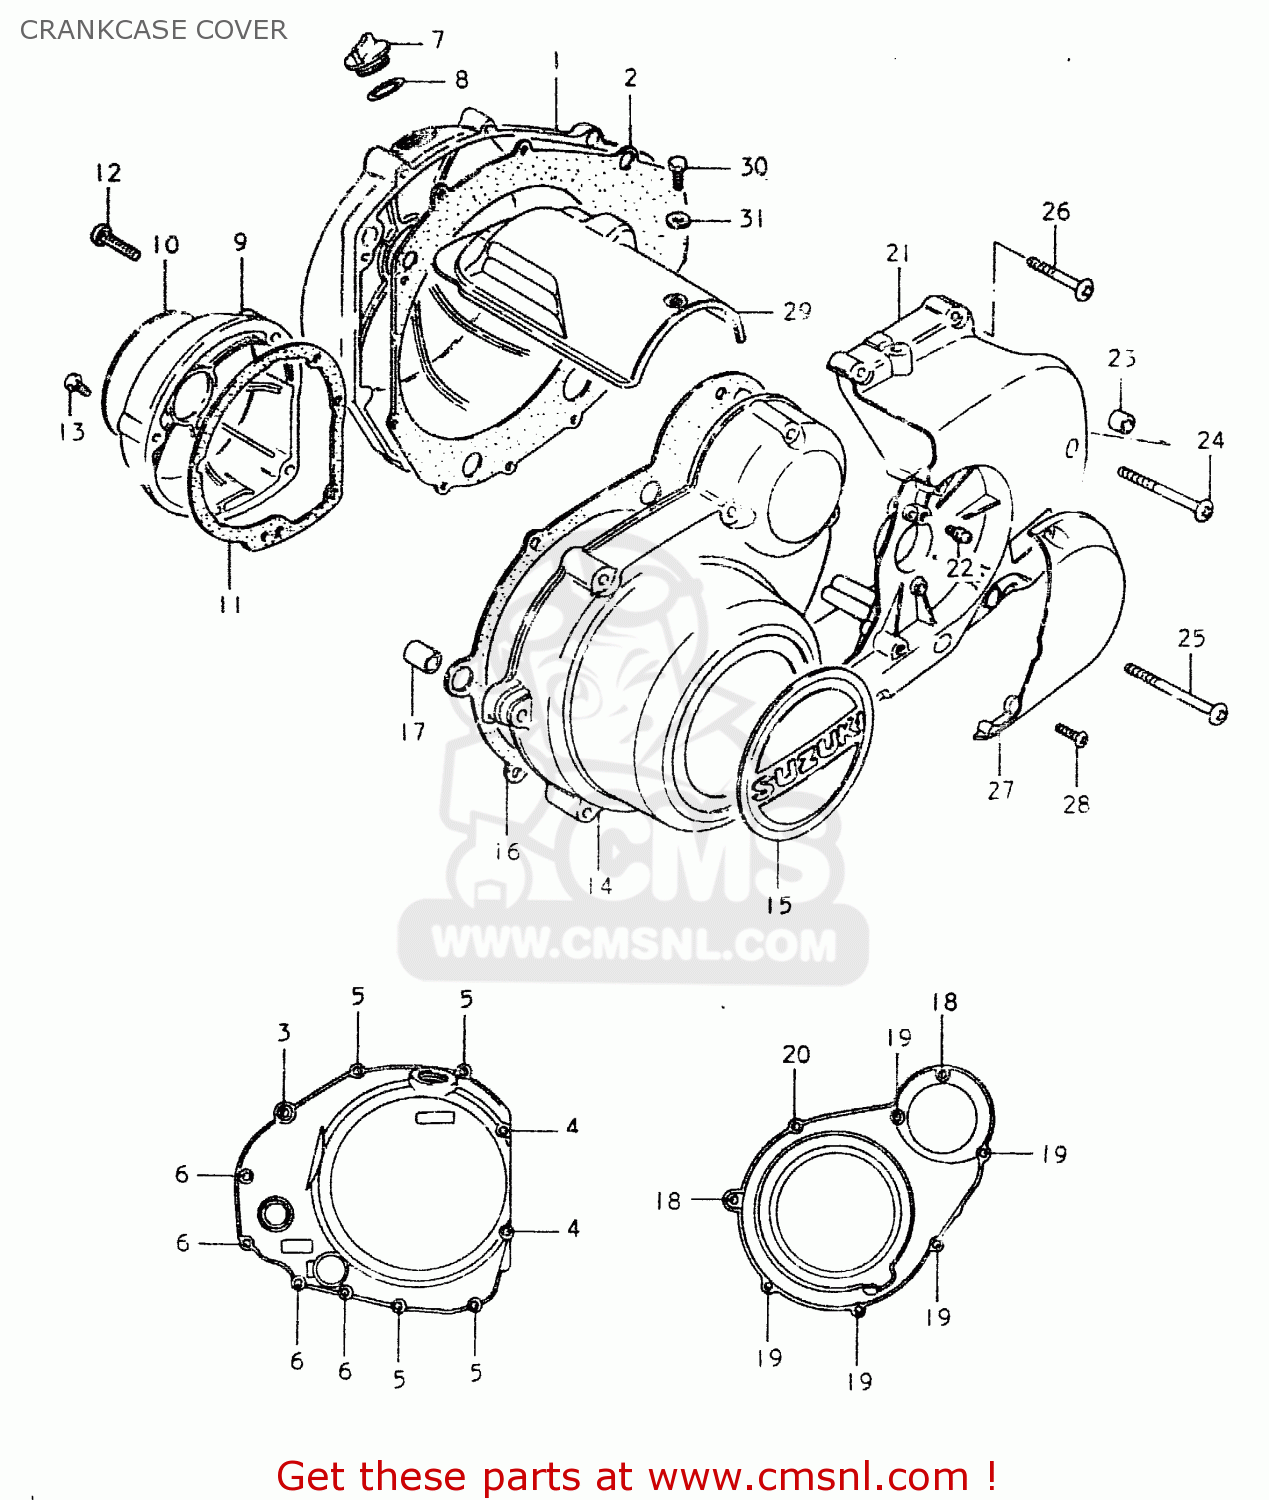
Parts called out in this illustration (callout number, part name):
1	COVER,CLUTCH
2	GASKET,CLUTCH COVER (MCA)
3	SCREW (6X35)
4	SCREW
5	SCREW
6	SCREW
7	CAP
8	O RING(D:2.2,ID:32)
9	COVER,CONTACT BREAKER
10	EMBLEM,CONTACT BREAKER COVER
11	GASKET,CONTACT BREAKER COVER (NAS)
12	SCREW
13	SCREW
14	COVER
15	EMBLEM,MAGNETO COVER
16	GASKET,MAGNETO COVER (MCA)
17	PIN
18	SCREW (6X45)
19	SCREW
20	SCREW (6X35)
21	CRANKCASE SET
22	NIPPLE
23	PIN
24	SCREW
25	SCREW 6X80
26	SCREW 6X30
27	CAP,CLUTCH RELEASE ADJUST
28	SCREW
29	COVER,STARTER MOTOR
30	BOLT
31	WASHER
